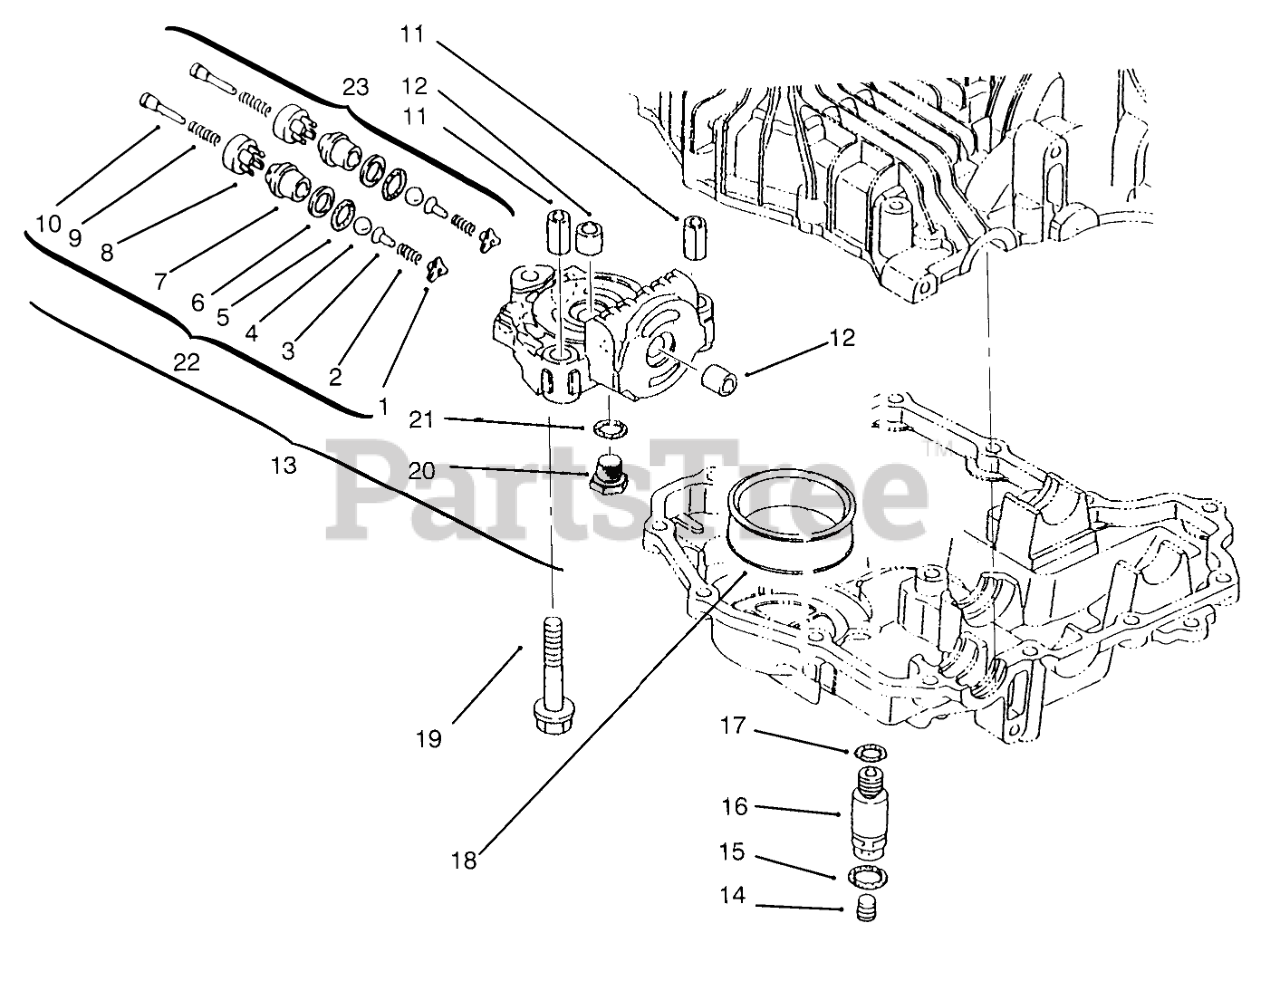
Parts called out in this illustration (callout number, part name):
1	Holder-Bypass (Only On: 72043,72063,72103)
5	Packing (Only On: 72043,72063,72103)
6	Ring-Back Up (Only On: 72043,72063,72103)
11	Pin-Knock (Only On: 72043,72063,72103)
12	Bushing (Only On: 72043,72063,72103)
13	Case INCL 11 -12 & 20-23 (Only On: 72043,72063,72103)
14	Plug (Only On: 72043,72063,72103)
15	Packing (Only On: 72043,72063,72103)
16	Connector (Only On: 72043,72063,72103)
17	Packing (Only On: 72043,72063,72103)
18	Filter (Only On: 72043,72063,72103)
19	Bolt (Only On: 72043,72063,72103)
20	Plug (Only On: 72043,72063,72103)
21	Packing (Only On: 72043,72063,72103)
22	Valve ASM A1 INCL 1 -10 (Only On: 72043,72063,72103)
23	Valve ASM A2 (Only On: 72043,72063,72103)
